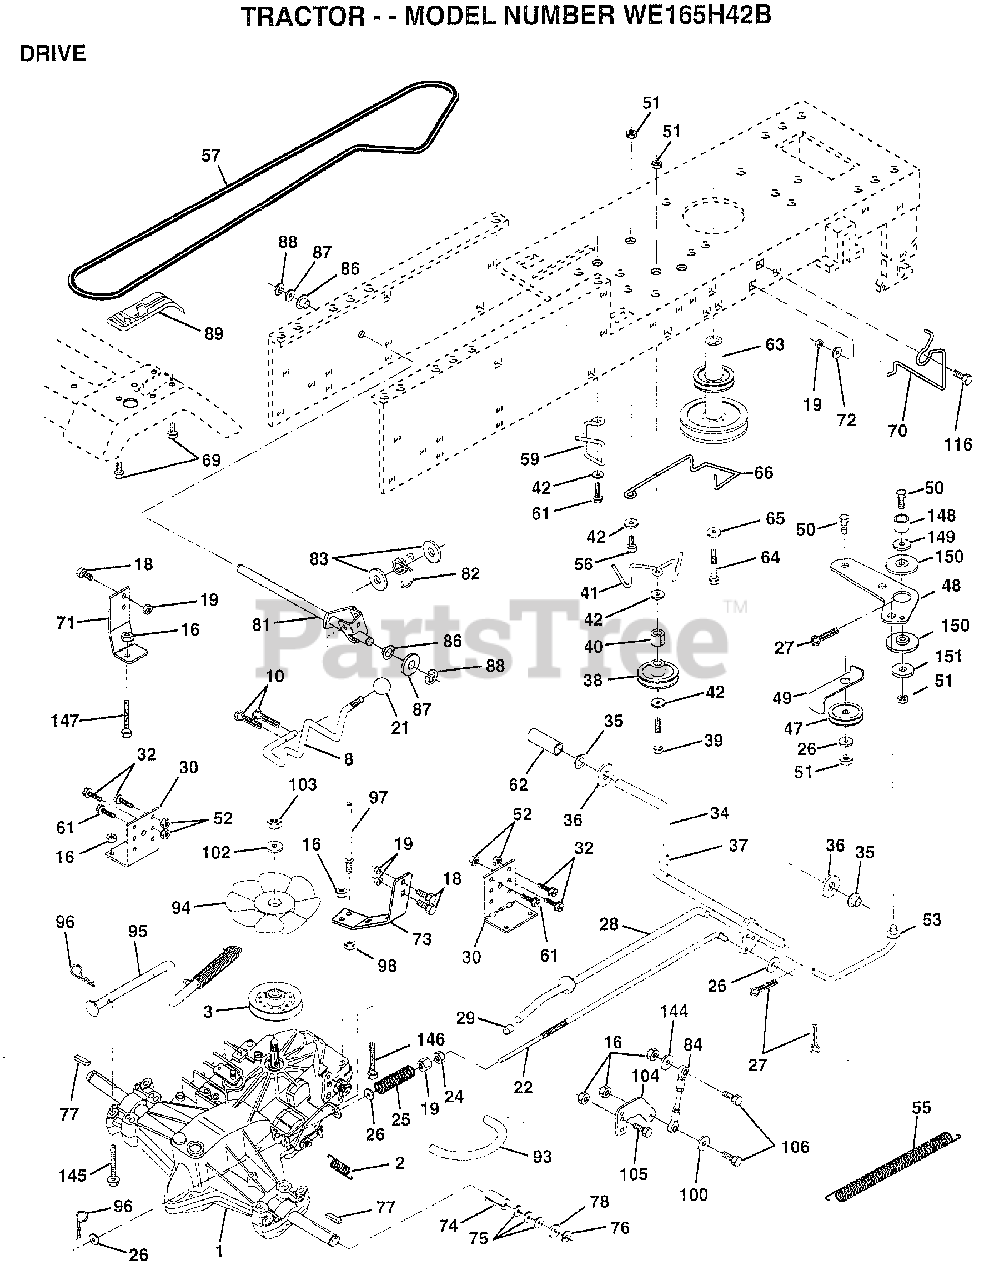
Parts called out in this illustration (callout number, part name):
1	TRANSAXLE.3100650
2	SPRING RET BRAKE
3	PULLEY.TRANSAXLE
8	ROD SHIFT FEND LT
10	PIN COTTER 1/8
16	NUT
18	BOLT
19	NUT
21	KNOB T (1/2-HOLE)
22	ROD.BRAKE.HYDRO.
24	NUT
25	SPRING ROD LT
26	WASHER
27	COTTER PIN
28	ROD.BRAKE.PARK.LT
29	PLUNGER CAP T
30	TRANSAXLE MTG BKT
32	BOLT
34	SHAFT ASM-PEDAL F
35	NYLON BEARING
36	WASHER LT
38	PULLEY.IDLER.FLAT
39	BOLT
40	SPACER T
42	WASHER
48	BELLCRANK.CLUTCH
49	RETAIN BELT
53	"LINK, CLUTCH T"
55	"SPRING, RETURN LT"
57	"BELT.GD DRV 82"""
59	KEEPER BELT CNTSP
61	SCREW
62	PEDAL COVER T
63	PULLEY.ENGINE
64	BOLT
65	LOCKWASHER
66	KEEPER-BELT
69	SCREW HEXWSH H-L
70	KEEPER BELT ENG
71	STRAP TORQ LH HYD
72	WASHER
73	"STRAP-TORQUE,RH"
74	SPACER SPLIT
76	E-RING LT
77	SQUARE KEY
78	WASHER
81	SHAFT.CROS.20.HYD
82	"SPRING,TORSION"
83	WASHER
84	ROD.TIE
86	BUSHING
87	WASHER D
88	KLIP RING
93	"LINE FUEL HYD 4"""
94	"FAN 7"" HYDRO"
97	BOLT KEEPER RH
98	NUT
100	WASHER M
102	WASHER BELLEVILLE
104	ARM CONTROL HYDRO
105	SCREW CAP 5/16-18
106	BOLT
116	BOLT RDHD 3/8-16
144	WASHER
145	BOLT.HEX.FLGHD
146	BOLT.HEX.FLGHD.
147	BOLT.HEX.FLGHD
149	SPACER RETAINER
150	BUSHING.NYLON
151	WASHER
